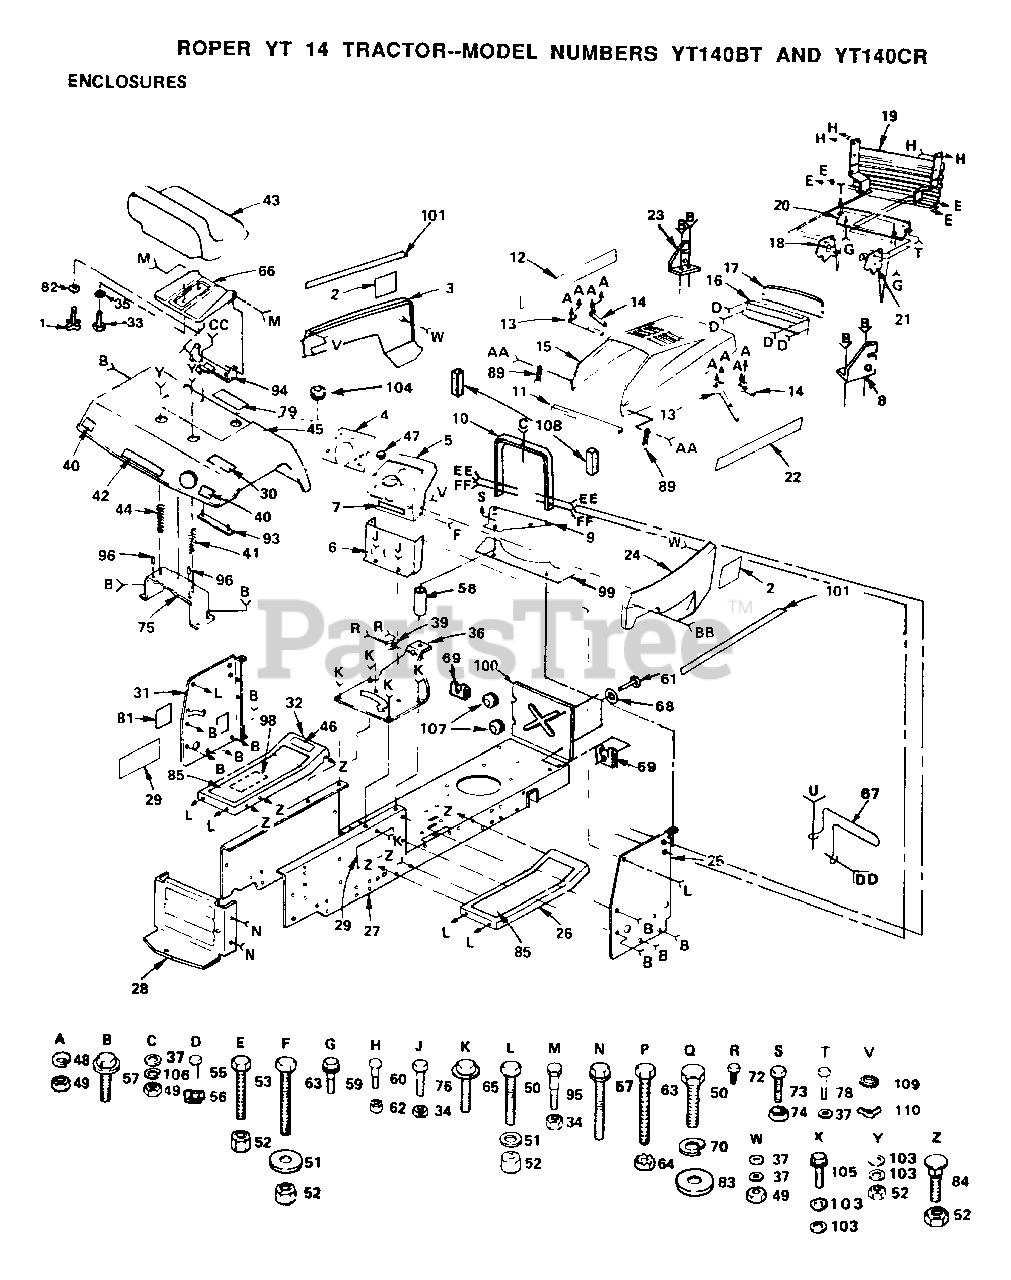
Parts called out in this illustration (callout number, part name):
1	"KNOB 1/2"" YT"
4	DECAL-DASHBOARD (GTK181AT ONLY)
6	LOWER DASH
8	SUPPORT RH YTH
11	FOAM STRIP T
17	LENS LT
18	SUPPORT LH YTH
21	SUPPORT RH YTH
23	SUPPORT LH YTH
30	DECAL-CAUTION
31	DASH PANEL T
32	FOOTREST LH YT
33	BOLT T
37	LOCKWASHER GT
40	REFLECTOR-TAIL YT
46	DECAL T
47	PLUG-DASH T
51	WASHER
53	BOLT
56	"""J"" FASTENER LT"
57	SCREW
58	SPACER-SPLIT YTV
59	SCREW
60	BOLT T
64	NUT
65	SCREW LT
67	SCREW
68	RETAINER LT
69	RECEPTACLE LT
70	LOCKWASHER
73	BOLT
78	SCREW HEX CRT
83	WASHER T
84	BOLT
89	HOOD LATCH T
96	NUT-PUSH YT
103	WASHER
104	GROMMET T
105	SCREW GTV
106	LOCKWASHER
108	STRIP - FOAM
109	LOCKWASHER GT
